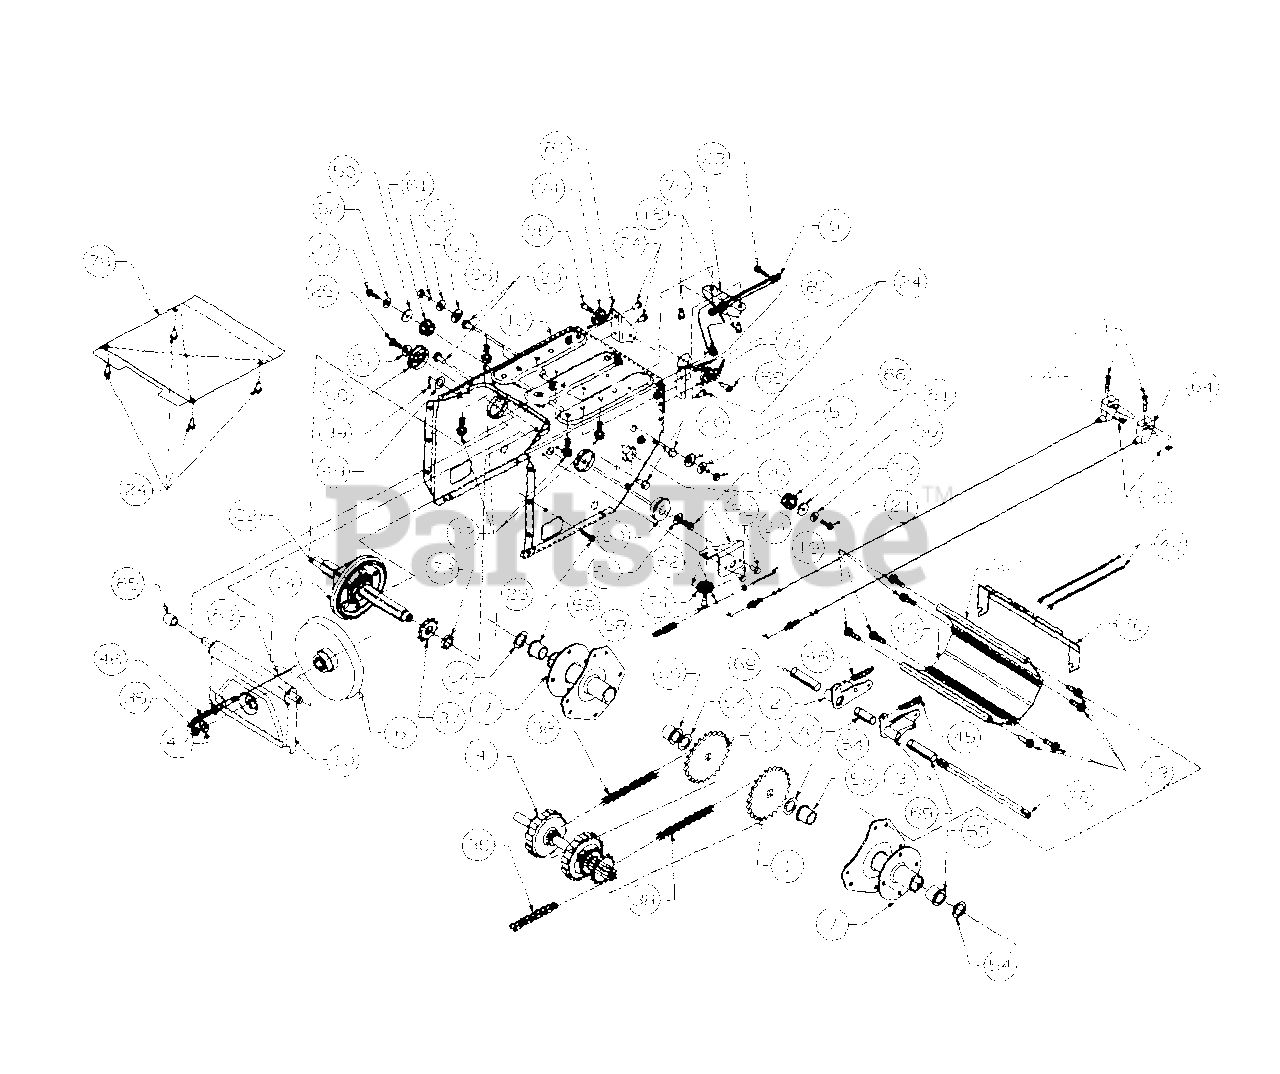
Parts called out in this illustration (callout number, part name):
1	Axle Assembly
2	Dog Assembly - R.H.
3	Dog Assembly - L.H
4	Shaft Assembly
6	Disc Assembly
14	Wheel Assembly Friction
15	Screw
20	Screw
25	Screw
30	Nut Flange
39	Pin Cotter
40	Housing Track
42	Cable Tie
45	Spring
46	Spring
47	Washer-Bell
49	Washer-Flat
50	Washer-Flat
51	Washer-Bell
52	Washer-Bell
54	Washer-Flat
56	Lubricant
58	Screw-Shoulder
59	Bearing-Flange
60	Bearing-Ball
61	Bearing-Hex Flange
62	Cable-Auger Clutch
63	Cable-Drive Clutch
64	Cable with Trigger Lever
66	Spacer-Shoulder
69	Spacer-Split
70	Spacer-Split
73	Spacer
74	Roller-Cable
